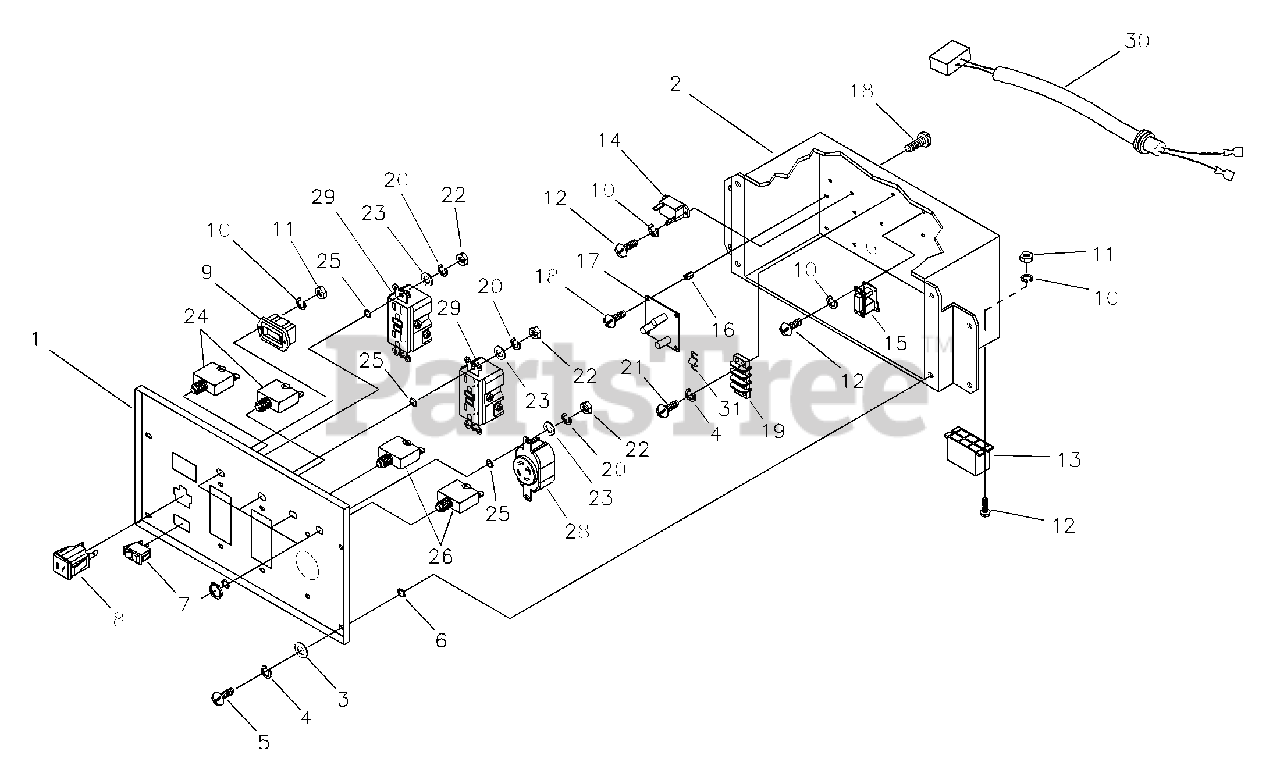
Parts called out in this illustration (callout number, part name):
1	PANEL, Control
2	BOX, Control Panel
4	WASHER, Lock
7	SWITCH, Rocker
8	OUTLET, 12VDC, Snap
9	METER, Hour
10	WASHER, Lock
13	HOUSING, Receptacle
14	BREAKER, Circuit
15	TRANSFORMER, Idle Cnt
16	STANDOFF, Hex
17	PCB, Idle Control
19	STRIP,Terminal
20	WASHER, Lock
24	BREAKER, Circuit
26	BREAKER, Circuit
27	JUMPER,Terminal Block
28	OUTLET, 120/240V, 30A
29	OUTLET, 120V, 20A, Duplex. GFCI
30	HARNESS,Wire
